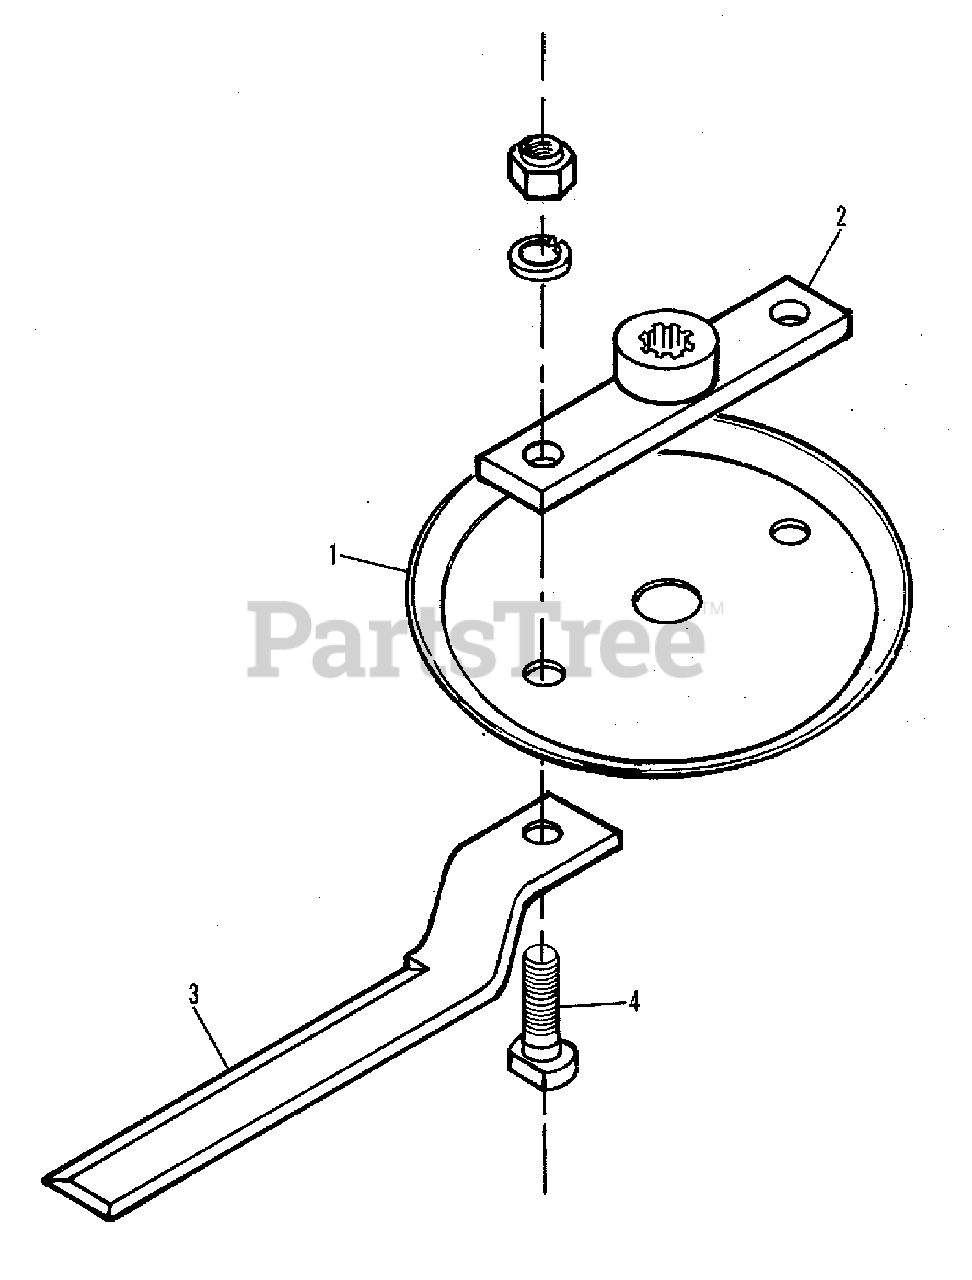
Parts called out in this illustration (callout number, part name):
1	DISK, Stump Jumper
3	BLADE, Cutting
4	BOLT ASSEMBLY
